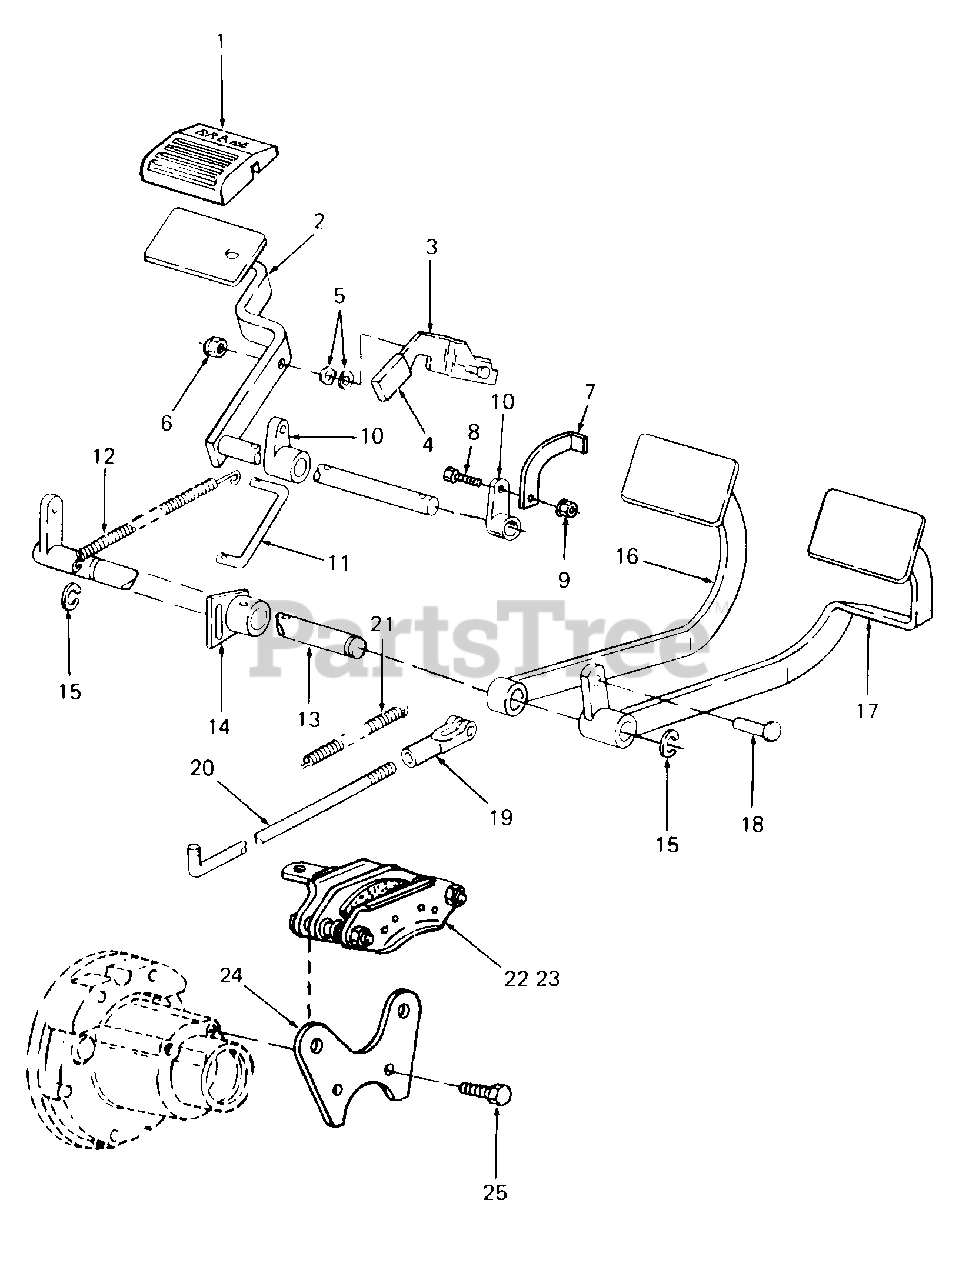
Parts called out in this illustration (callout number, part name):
1	Pad, Brake Pedal
5	Washer, Wave, 1/4 Dia
6	Nut, Hex Insert Lock, 1/4-20
8	Screw, Hex Cap, 3/8-16 X.75 Lg GR5
9	Nut, Hex Flanged Lock, 3/8-16 GR5
11	Rod, Center Brake 1
12	Spring, Extension, .50 OD X 7.32 Lg
13	Shaft Assy, Brake
14	Plate Arm Assy, Parking Brake
15	Ring, Retaining 2
18	Pin, Clevis, 3/8 Dia X 1.56 Lg
19	Clevis, Adjustment
20	Rod, Brake
21	Spring, Extension,.66 OD X 3.3 Lg
22	Brake Kit, RH Caliper
24	Bracket, Brake Mounting
25	Screw, Hex Cap, 5/16-18 X 1.0 Lg GR5
